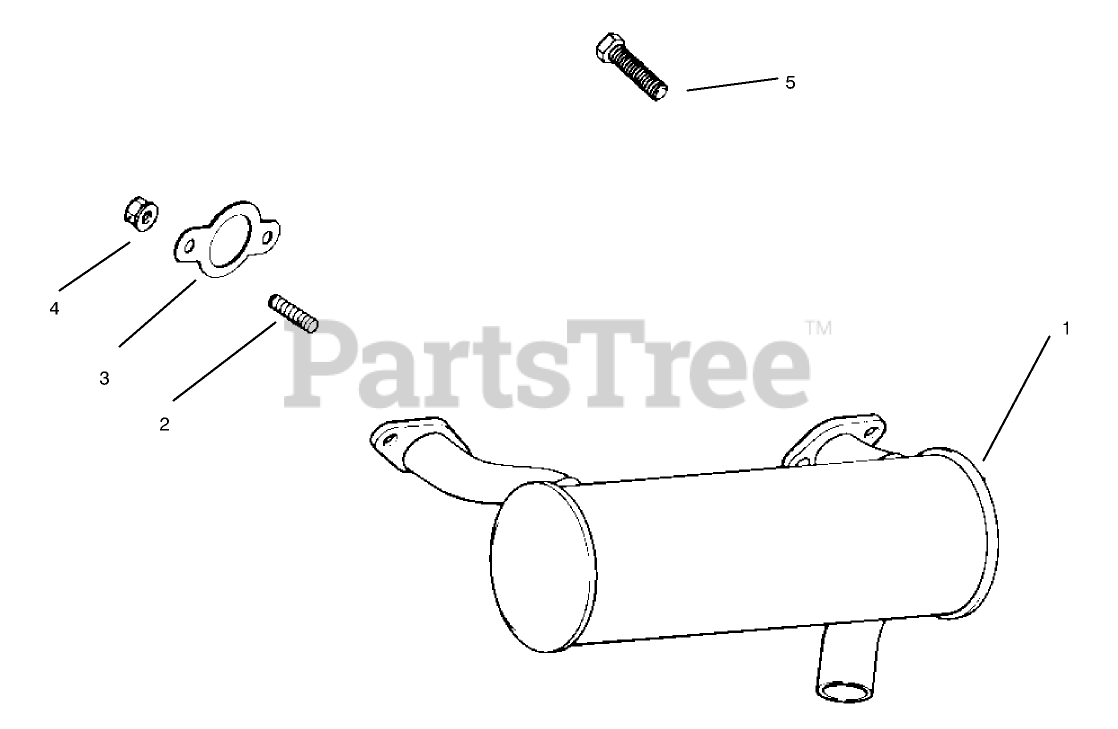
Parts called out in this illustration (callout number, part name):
1	Muffler
2	Stud-Muffler
3	GASKET-EXHAUST
4	NUT-HF
5	SCREW-HHF
